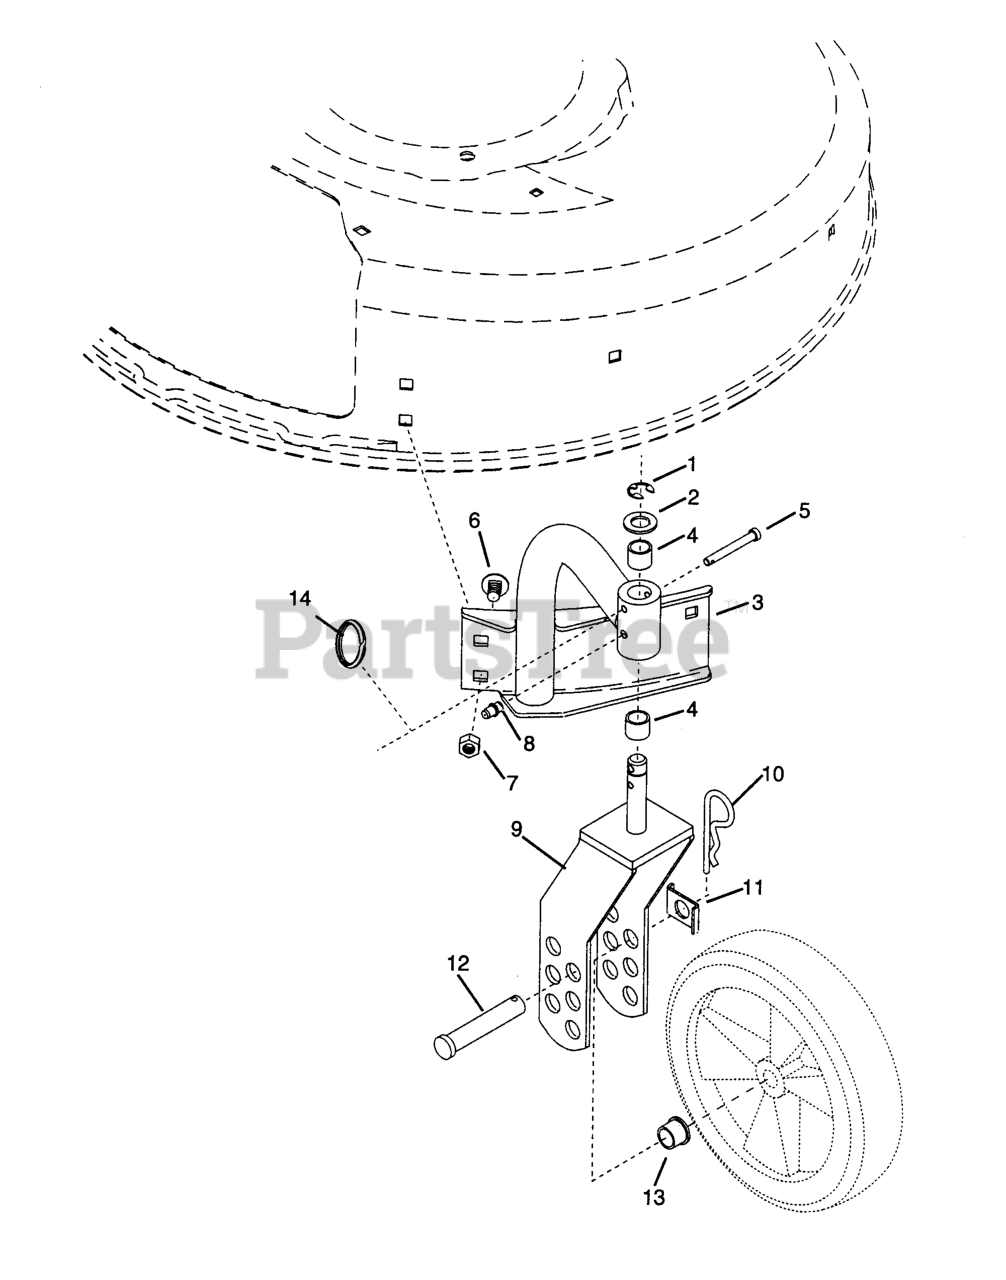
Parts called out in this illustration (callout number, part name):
1	RG-RTNG-EXT .625X.042
2	WSHR-FL-STL .630X1.005X.062 YZ
3	RIGHT MOUNT ARM WELDMENT
4	BSHG-SLV .625X.750X.500 BR
5	PIN-CLEV .25X1.75 YWZC
6	@BLT-RDHDSQNK .31-18X.50 G5YZ
7	@NUT-HEX .31-18 YWZC
8	FTG-LUBE .25-28X.256 YWZC
9	WHEEL YOKE WELDMENT
10	PIN-HAIR-INT .15X.43X2.75 YWZC
11	AXLE TAB
12	PIN-CLEV .494X2.62 YWZC
13	BSHG-FLG .500X.625X.500X.750
14	KICKOUT RING YWZC
